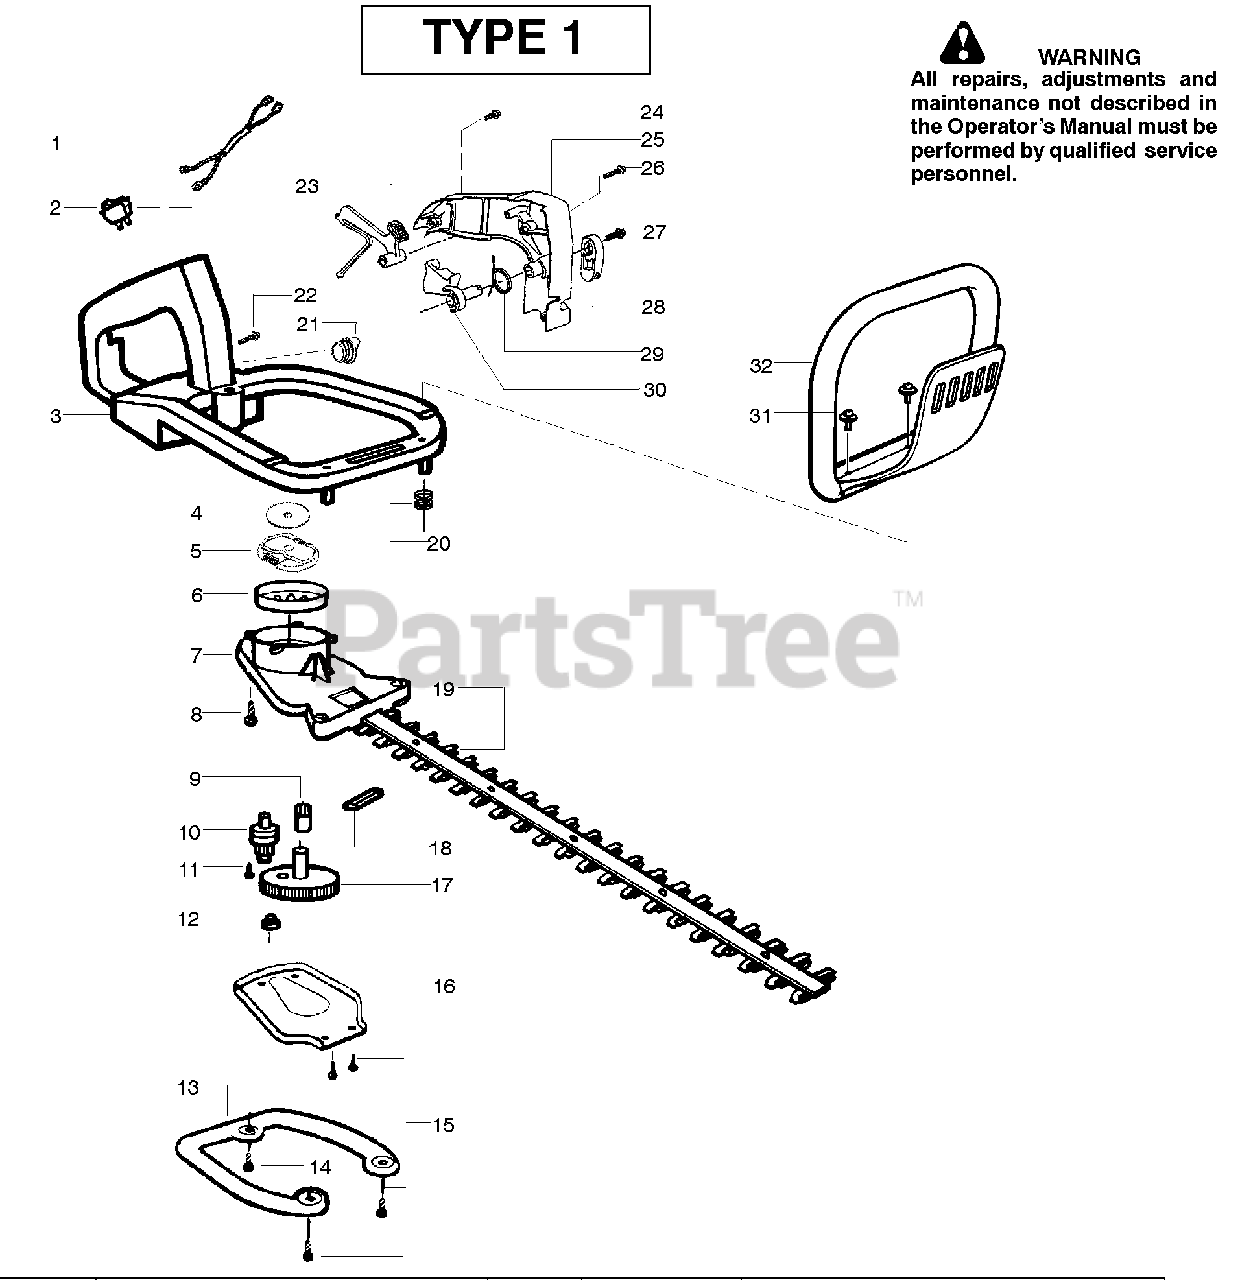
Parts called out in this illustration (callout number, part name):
1	Assy-Leadwire/Switch
2	Switch-Ignition
3	Assy-Rear Handle & Tank
4	Washer-Clutch (Kit)
5	Assy-Clutch (Kit)
6	Drum-Clutch (Kit)
7	Assy-Gear Box
9	Bearing-Gear
10	Assy-Pinion
11	Screw
12	Bushing-Blade
13	Plate-Isolator
16	Cover-Gear Box Plate
17	Kit-Drive Gear Ass'y.
18	Seal-Blade (Felt)
19	Assy-Blade 19"
21	Assy-Fuel Cap
23	Lockout-Throttle
25	Cover-Handle
28	Lever-Trigger
29	Spring-Trigger
32	Handle-Front
